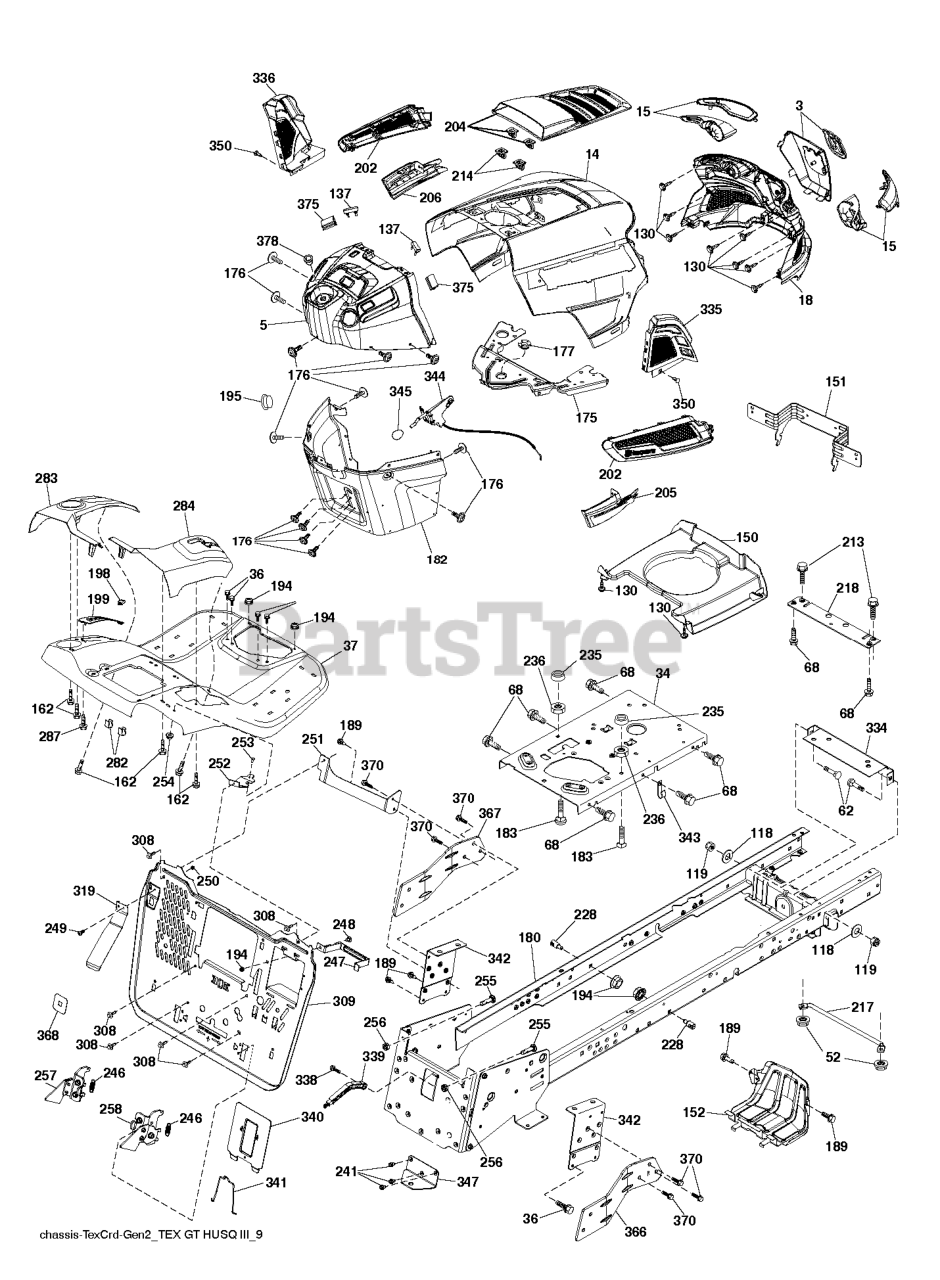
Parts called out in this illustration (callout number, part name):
14	HOOD.ASM.HUSQVARNA.GT.TEX.ORAN
15	Service Kit
36	SCREW 5/16"
37	FENDER.TEX.SRD.CRD.BASE
118	WASHER PLAIN WASHER 3/8 X 0.08
137	BUMPER DASH
150	AIR.DUCT.GTV.BLACK
151	BRACKET.PIVOT.HOOD.GT.HUSQ.II
152	SHIELD.BROWNING.PNT.GT.V2
175	PLATE.PNT.CROSSMEMBER.HUSQ/PRE
176	SCREW.#10-24X5/8.RN.QU
177	BUSHING STEERING
180	CHASSIS WELDMENT.CRD2.BKP_BLTS
182	DASH DASH LOWER
189	SCREW
195	PLUG.HOLE.DASH.LOWER.12V.BLK
198	INDICATOR.DECK.LIFT.RED
199	PLATE DECK LIFT
202	Vents
204	Vents
205	SIDE.TRIM.RH.GT.HUSQ.II
206	SIDE.TRIM.LH.GT.HUSQ.II.GRAY
213	SCREW HEXAGON HEAD SCREW 5/16-
214	CLIP.RETAINER.TINNER.
217	ROD.PIVOT.HOOD
218	X-PIECE.HOOD.STOP.NON/
228	STUD.W/"D"ANTI-ROTATION
236	NUT.CENTERLOCK.5/16-
246	SPRING.LTCH.BGR.GEN2.5.CRD.TEX
247	STRAP.BATTERY.TCRD.GEN2.5X431
248	BOLT.CARR.5/16-18X1/2
249	SCREW.BUTTONHD.10-24X1/2.(2 2)
251	BRACKET.PNT.LH.SUPP.BKPLT.EDIP
252	BRACKET.PNT.RH.SUPP.BKPLT.EDIP
253	BOLT CUP HEAD SQUARE NECK BOLT
254	NUT T
257	LATCH.ASM.BGR.LH.GEN2.5.STMPD
258	LATCH.ASM.BGR.RH.GEN2.5.STMPD
282	CLIP.RETAINER.CONSOLE.LT.HUSQ
283	CONSOLE.DECKLIFT.CRDII.498
284	CONSOLE.PEDAL.HYDRO
287	SCREW 1/4X20
308	BOLT.5/16-18UNCX3/4 W/SEMS.BLK
309	BACKPLATE.TEXCRD2.5.BAGGER.479
319	LEVER.PRSNC.BGR.TEX.CRD.GEN2.1
334	BRACKET.ENGINE
335	COVER.LOWER.DASH.RH.BLACK
336	COVER-LH.LOWER.DASH.GT2.BLACK
339	.WITCH.FULL BAGGER.INDICATOR
340	BATTERY.DOOR.TCRD.GEN2.5.MS479
341	LATCH.BATTERY.DOOR.TCRD
342	SUPPORT.PNT.FENDER.CRD.TEX
343	CLIP CLIP
344	CONTROL.EZ.MULCH.TEX/CRD
345	RP KNOB.OVAL.TAPERED.3/8-16BLK
347	HITCH HITCH TOW TEX CRD GEN 2
350	CLIP.X-MAS.TREE
367	Brackets
368	FULL.LEVER.BAGGER.TEX.CRD
370	SCREW 3/8-16X1
375	BUMPER CLIP-ON. DASH 1"
378	BUSHING FLANGE; PLASTIC
